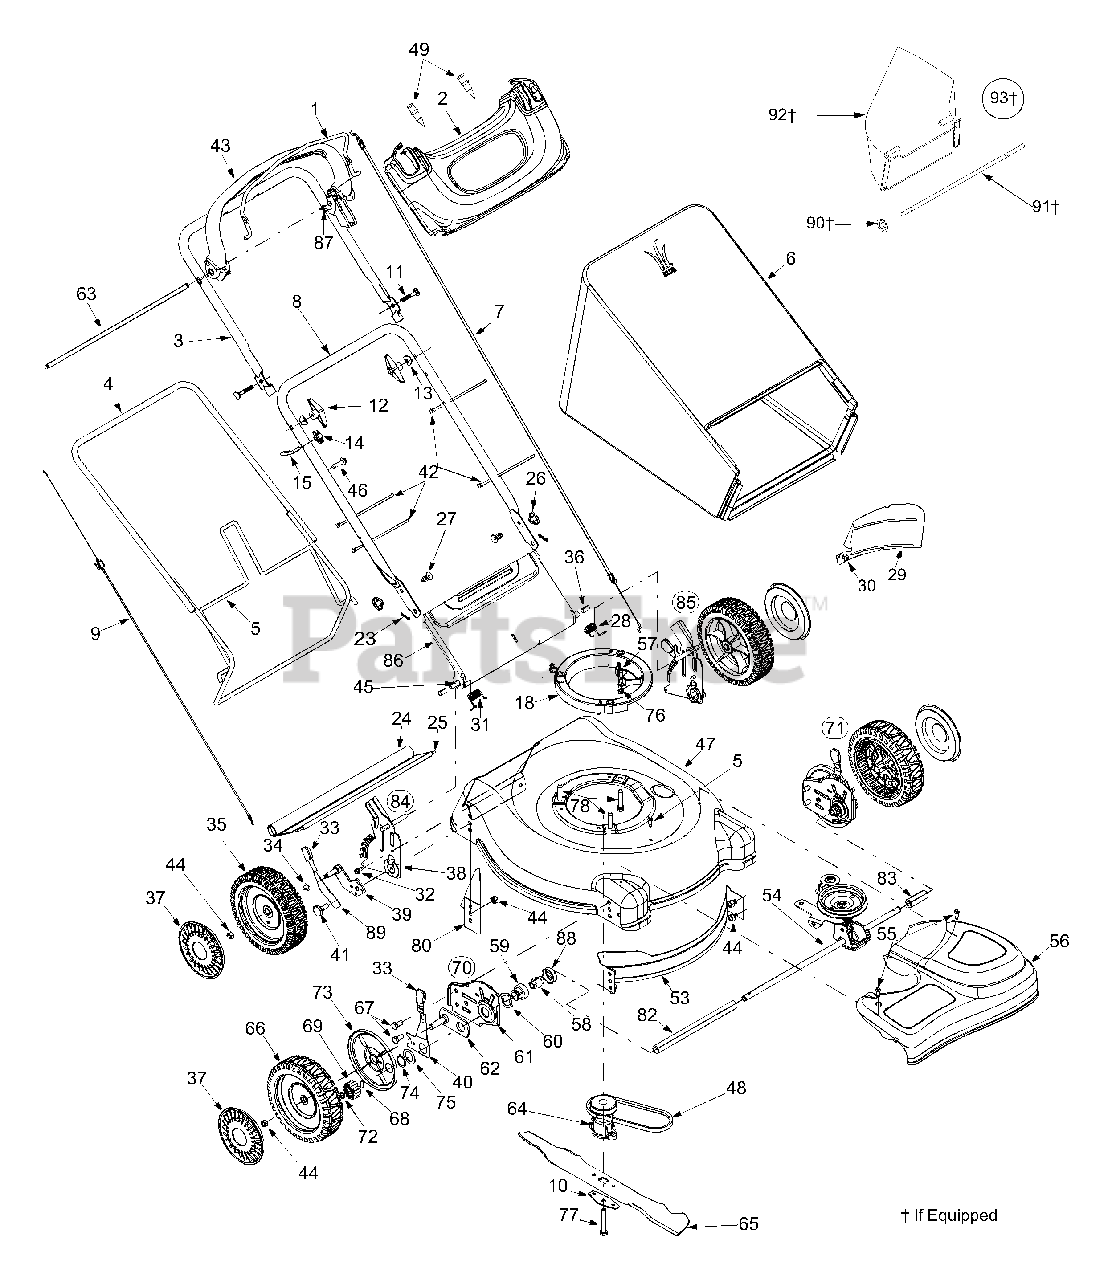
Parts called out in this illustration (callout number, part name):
2	Handle Panel
5	Shoulder Screw
6	Grass Bag
7	Control Cable
9	Drive Cable
10	Blade Bell Support
11	Carriage Bolt, 5/16-18 x 2.00
12	Handle Knob
13	Saddle Washer
14	Wing Nut
15	Rope Guide
18	Engine Spacer Assembly
23	Hairpin Clip
24	Rear Trail Shield
25	Trail Shield Wire
26	Wing Nut
27	Hex Carriage Screw
28	Torsion Spring LH
30	Scr. AB 1/4-14 x 0.625"
31	Torsion Spring RH
32	Hex Scr. w/ Wash. 1/4-20 x 0.625"
33	Knob
34	Wave Washer.510 x.750 x.017
35	Wheel, 8 x 2.125
36	Spacer,.390OD x.810ID x.950"
37	Hubcap: Radial Spoke Yellow
38	Handle Bracket RH
39	Pivot Arm Assembly RH
40	Front Lever RH
41	Shoulder Screw
42	Cable Tie
43	Drive Handle
44	Flange Lock Nut, 3/8-16
45	Rear Door Pivot Rod
46	TT-Scr., 1/4-20 x 1.250
47	21" Rear Discharge Deck
48	V-Belt
49	Rivet
55	Shld. Screw
56	Front Drive Cover: Yellow
57	Belt Keeper Pin
58	Bearing Sleeve.50 I.D.
59	Bearing Support
60	Wave Washer
63	Control Rod
64	One Piece Blade Adapter
65	21" Mulching Blade w/ Star
66	Wheel, 8 x 2.125
67	Hex Screw 3/8-16
68	Dowel Pin
69	Gear 14T RH
70	Height Adj. Assembly RH Compl.
71	Height Adj. Assembly LH Compl.
72	Snap Ring
73	Wheel Dust Cap
74	Snap Ring
75	Washer DD 1.5" O.D.
76	Hex Nut 1/4-20
77	Hex Bolt
78	TT Screw
82	Slev. Spacer RH
83	Slev. Spacer LH
84	Handle Bracket Assembly RH Compl.
85	Handle Bracket Assembly LH Compl.
86	RD Chute Door
87	Bail Stop
88	Bearing Retainer
89	Spring Lever
90	Nut: Spd.3125ID
91	Rod
92	Side Discharge Adapter
93	Chute Deflector Complete
